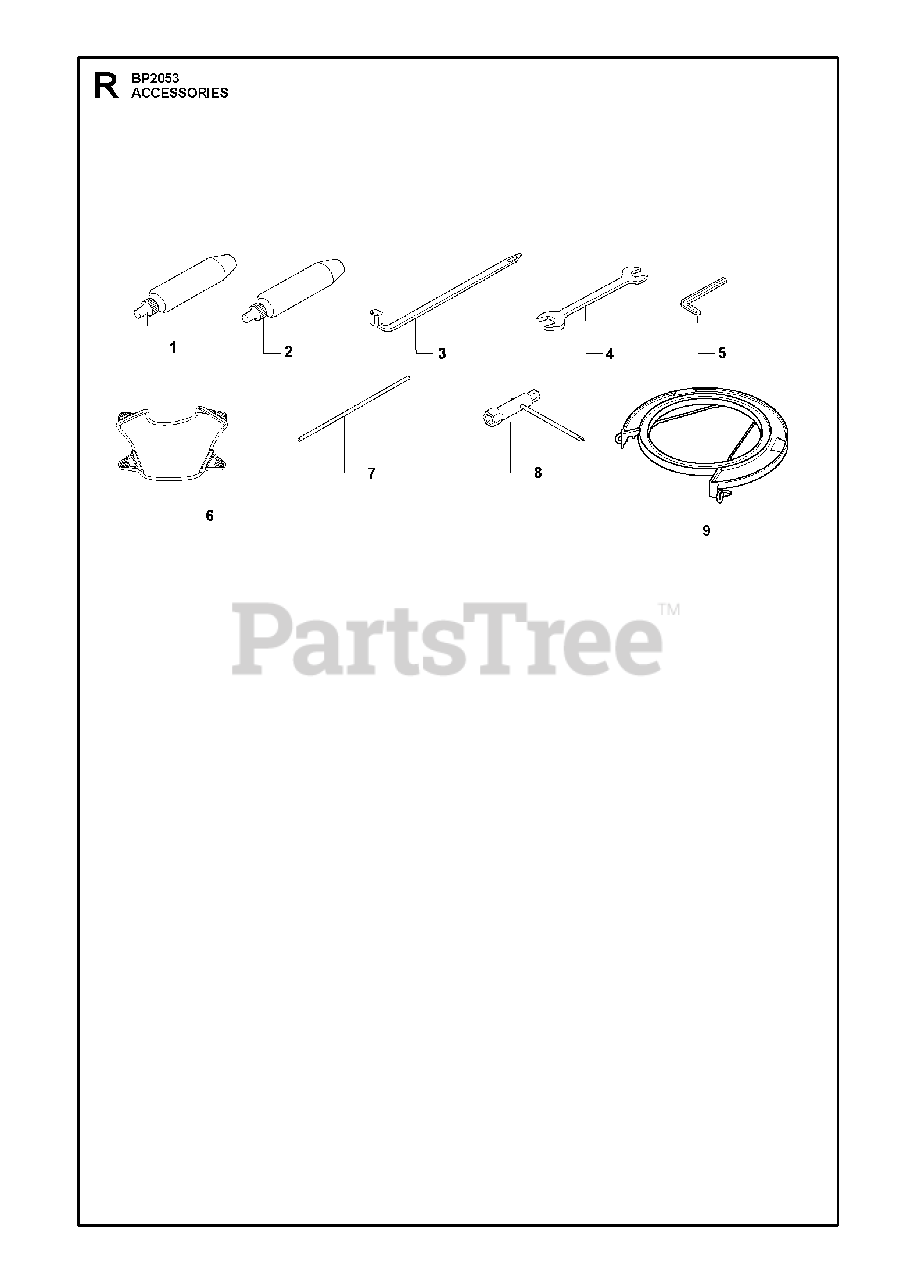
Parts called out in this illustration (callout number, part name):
1	BEVEL GEAR GREASE
4	U-SPANNER NLA
5	L-KEY WRENCH
6	TRANSPORT GUARD
8	COMBI TOOL
9	TRANSP.GUARD
